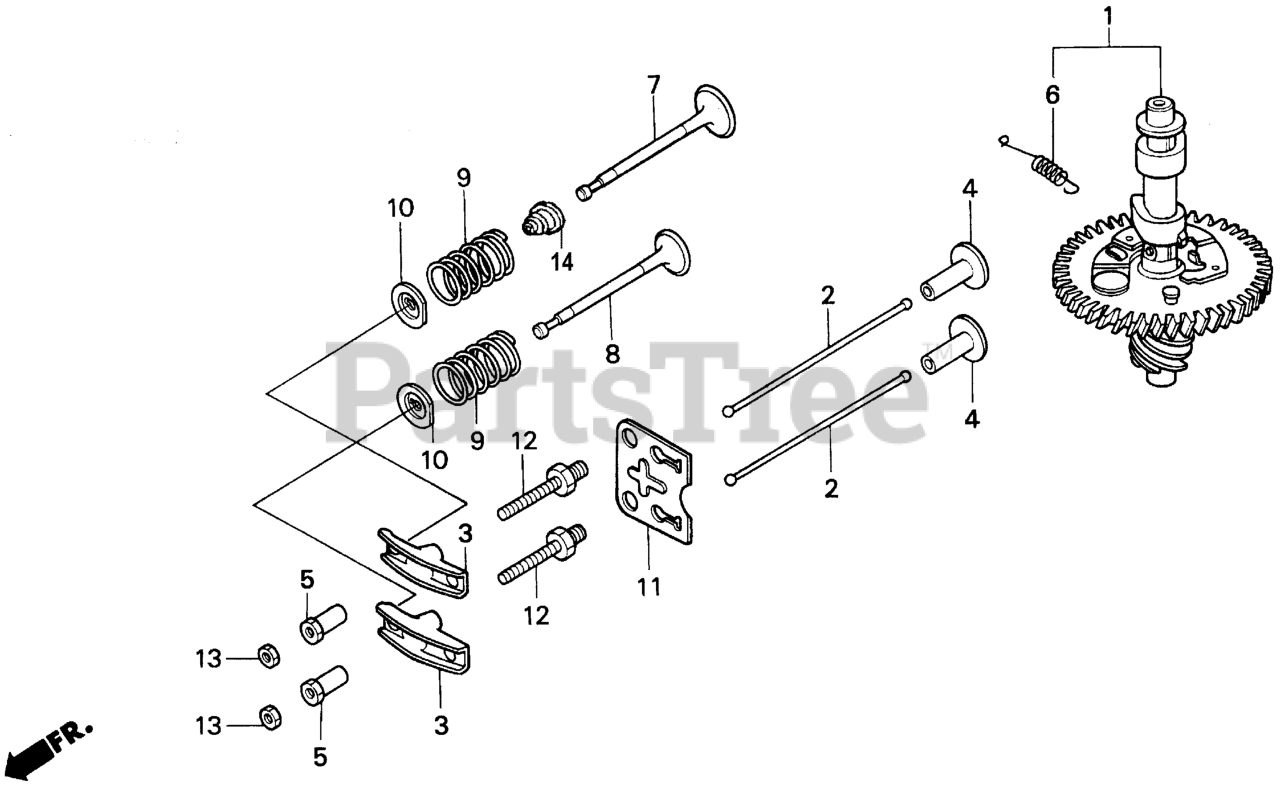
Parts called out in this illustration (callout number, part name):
1	CAMSHAFT ASSY.
2	ROD, PUSH
3	ARM, VALVE ROCKER
4	LIFTER, VALVE
5	PIVOT, ROCKER ARM
6	SPRING, WEIGHT RETURN
7	VALVE, IN.
8	VALVE, EX.
9	SPRING, VALVE
10	RETAINER, IN. VALVE SPRING
10	RETAINER, VALVE SPRING (EXHAUST SIDE)
11	PLATE, PUSH ROD GUIDE
12	BOLT, PIVOT (8MM)
13	NUT, PIVOT ADJ.
